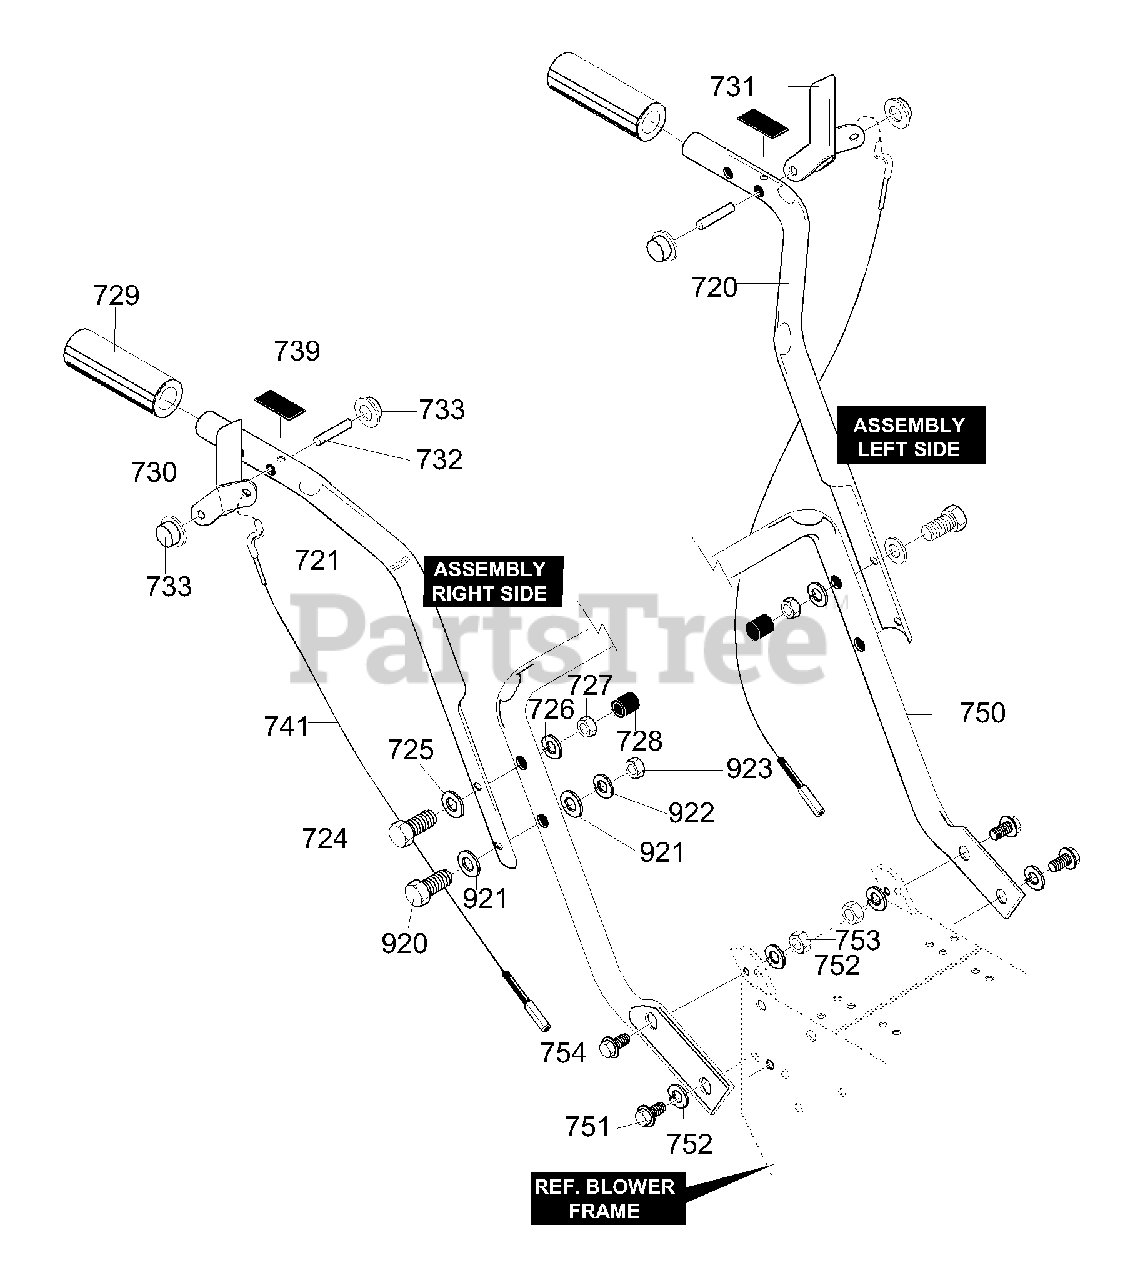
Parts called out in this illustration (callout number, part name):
720	UPPER HANDLE LH
721	UPPER HANDLE RH
724	SCREW, 3/8-16X3.00
725	FLATWASHER .406X.81X.065
726	WASHER, RGSPTLK .393X.68X.10
727	NUT, 3/8-16 REGHEXTRLK
728	STOP, PLASTIC .375
729	GRIP, HANDLE
730	HANDLE, CLUTCH RH
731	HANDLE, CLUTCH LH
732	PIN, PIVOT
733	PUSH ON CAP
739	BUMPER, RECT
741	CABLE, CLUTCH
750	HANDLE, LOWER
751	SCREW, 5/16-18X.75 WAHHTAP
752	WASHER, HVSPTLK .328X.60X.09
753	NUT 5/16-18 REGHEX
754	SCREW, 5/16-18X.75
920	SCREW, 3/8-16X2.00
921	FLATWASHER .406X.81X.065
922	WASHER RGSPTLK .393X.60X.10
923	NUT, 3/8-16 REGHEXCTRLK
